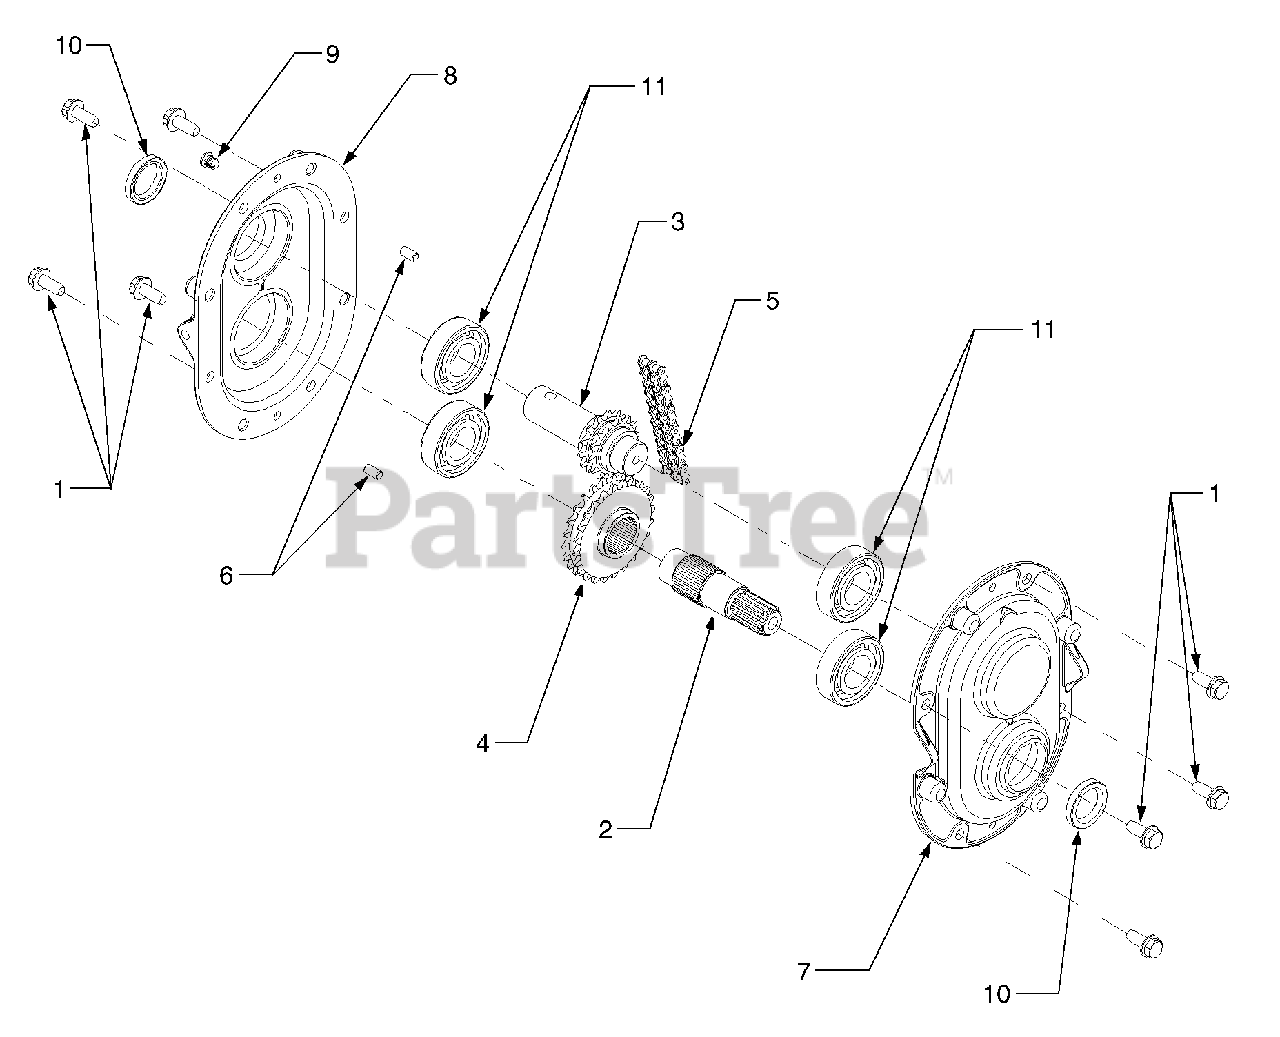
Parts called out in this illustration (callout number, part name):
1	Screw, Hex Wash. Hd. Tapp 5/16-18 x .75
2	Shaft, Output
3	Shaft, Input (w/ sprocket)
4	Sprocket, Drive
5	Chain, Endless, #35-2 x 34 Links
6	Dowel Pin, 1/4 x 1/2
7	Housing, Gear
8	Housing, Gear
9	Plug, 1/4 x .437
10	Seal, Oil
11	Bearing, Ball
